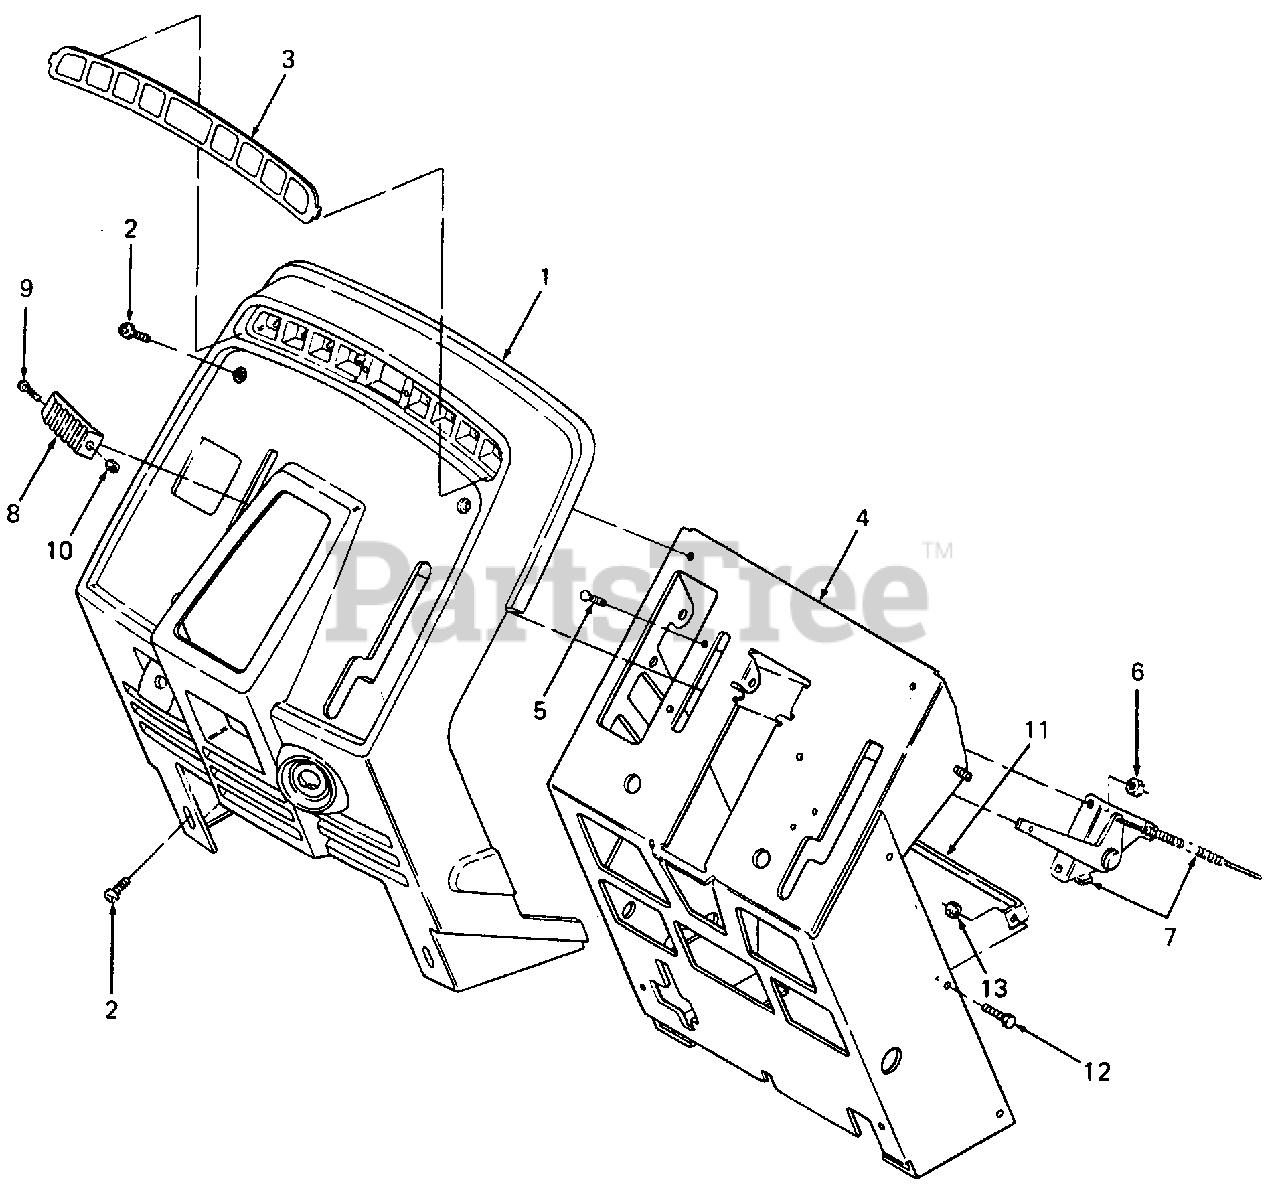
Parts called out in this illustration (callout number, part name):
1	Panel, Instrument
2	Screw, Pan Hd Cutting, #10-24 X .75 Lg
3	Label, Dash
6	Nut, Hex Keps, #10-32
7	Control, Throttle
8	Knob, Throttle
9	Screw, Cross Rec Truss Hd, #8-32 X .38 Lg
10	Nut, 8-32
11	Bracket, Harness
12	Screw, Hex Cap, 1/4-20 X .50 Lg GR5
13	Nut, Hex Patch Lock, 1/4-20
